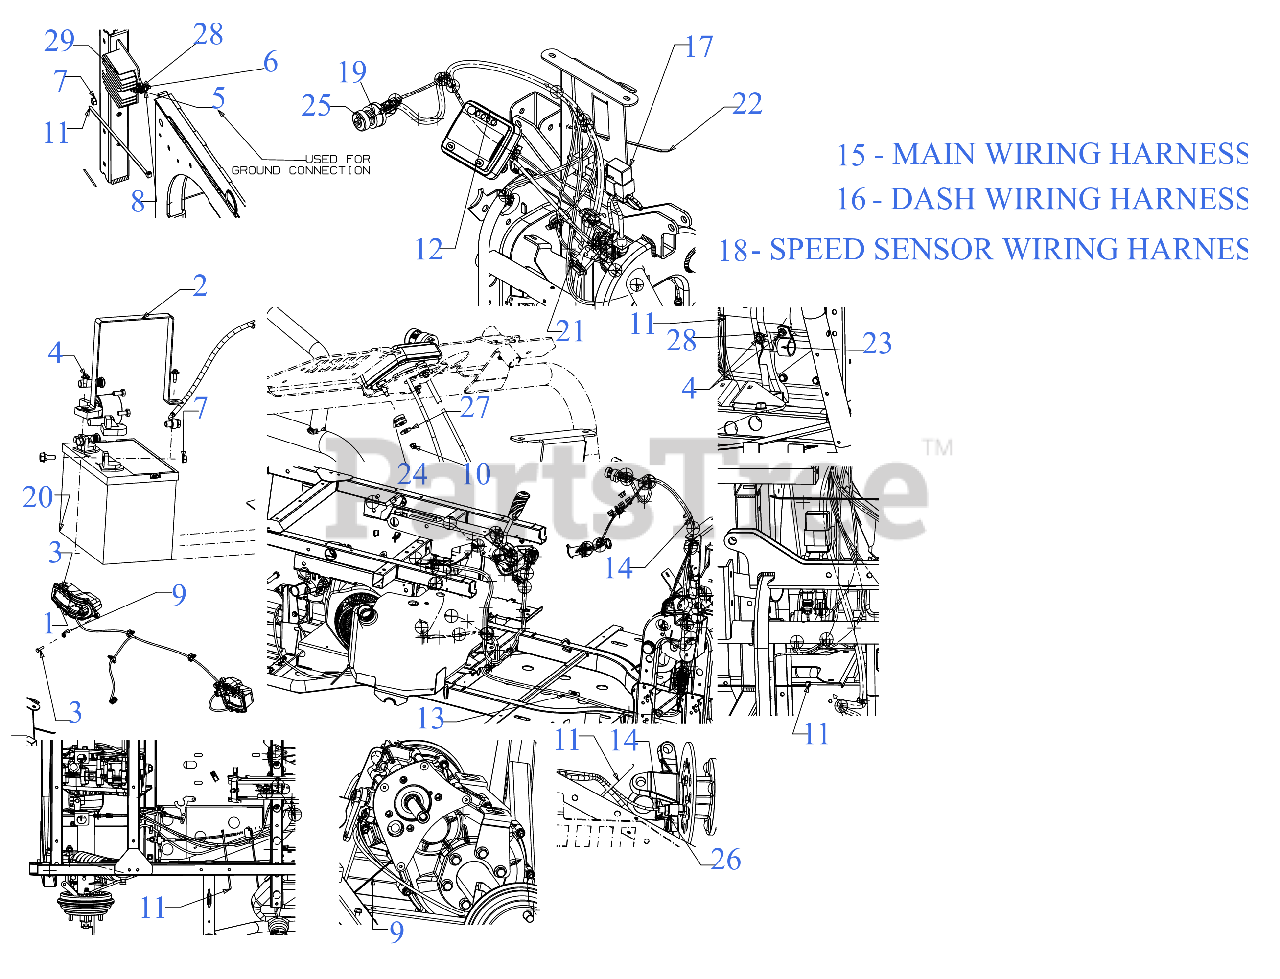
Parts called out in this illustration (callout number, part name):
1	LED HEADLIGHT ASSEMBLY
3	SCREW 1/4-20 X1.00 GR5
4	SCREW M6-1 x .625
5	SCREW 1/4-20 x .750
6	SCREW 1/4-20X.75 GR5
7	SEMS NUT 1/4-20
8	FLANGE LOCK NUT
9	SQUARE NUT 1/4-20
11	7" CABLE TIE
12	INDICATOR GAUGE
13	TRANSMISSION JUMPER HARNESS
14	SPEED SENSOR CABLE
15	MAIN WIRING HARNESS
16	DASH WIRING HARNESS
17	REV LIMITER BOX
18	SPEED SENSOR WIRING HARNESS
19	KEY SWITCH
21	POWER RECEPTICAL
22	CABLE TIE
23	HOSE CLAMP 1.0"
24	GROMMET .28 x .50 x .50
25	KEY SWITCH COVER
26	FLAT WASHER
27	FLAT WASHER .28 ID x .74 OD x .063
